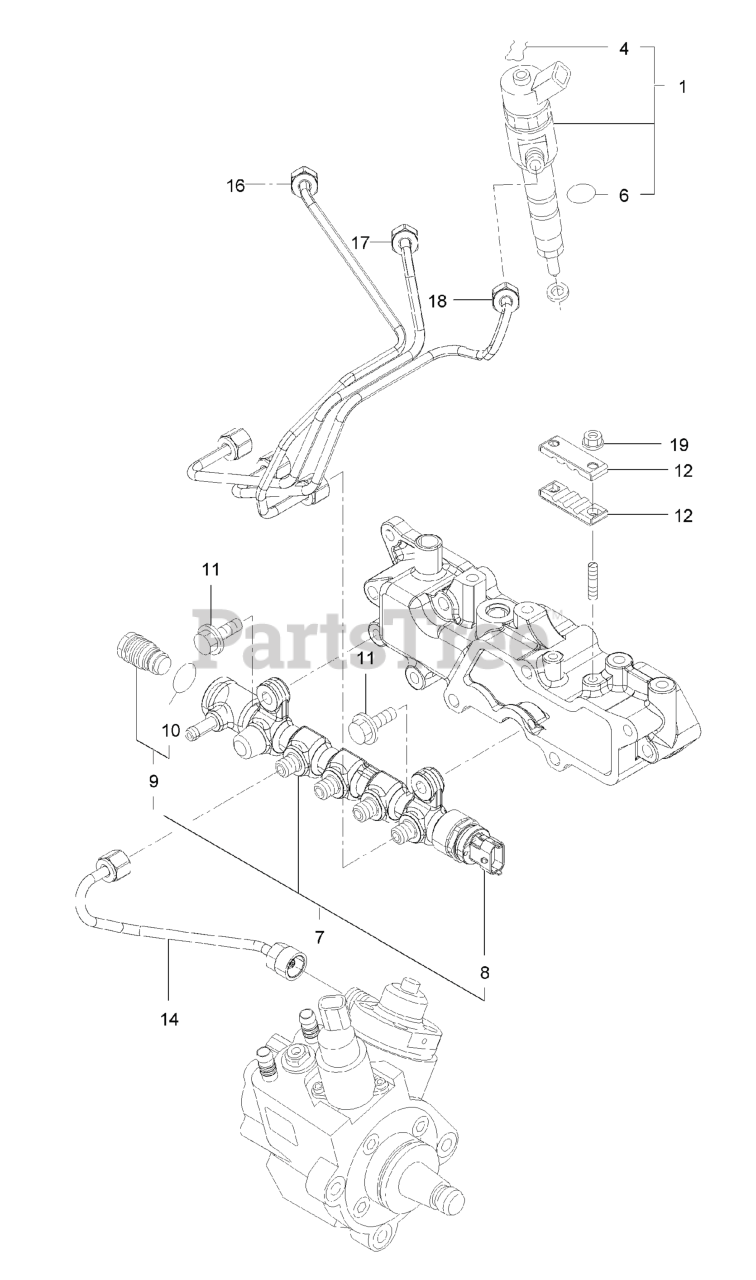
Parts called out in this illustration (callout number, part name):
1	INJECTOR ASM
4	RING-RETAINING
7	RAIL ASM
8	Sensor-Pressure, Rail
9	Valve ASM
12	RETAINER
14	RAIL IN PIPE ASM
16	INJECTION PIPE ASM
17	INJECTION PIPE ASM
18	INJECTION PIPE ASM
